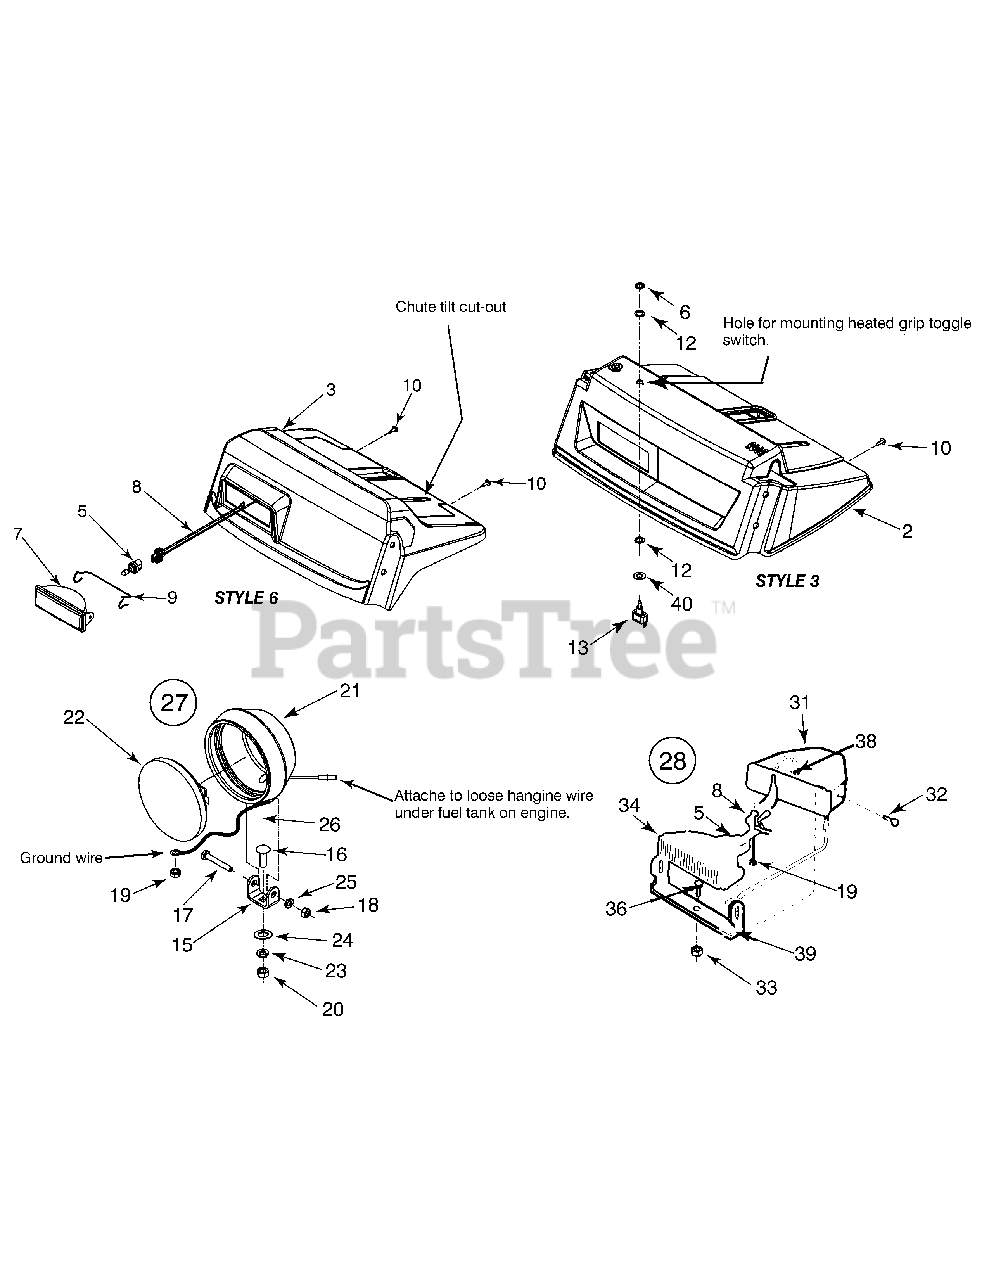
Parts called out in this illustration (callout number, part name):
2	Black Handle Panel (w/light cut out and chute tilt cut out) STYLE 3
2	Black Handle Panel (w/hole for top mounting light and chute tilt cut out) STYLE 3
2	Yellow Handle Panel (w/hole for top mounting light and chute tilt cut out) STYLE 3
2	Yellow Handle Panel (w/ light cut out, chute tilt cut out & heated grips) STYLE 3
2	Black Handle Panel (w/light cut out & w/o chute tilt cut out) STYLE 3
3	Grey Handle Panel (w/light cut out and chute tilt cut out) STYLE 6
3	Grey Handle Panel (w/hole for top mounting light and chute tilt cut out) STYLE 6
3	Black Handle Panel (w/hole for top mounting light and chute tilt cut out) STYLE 6
3	Black Handle Panel ( w/light cut out and chute tilt cut out) STYLE 6
5	Bulb #890, 12 V, 27 Watt
5	Bulb, #886, 12 V, 50 Watt (Style 3 w/heated grips)
7	Headlight Housing
8	Wire Harness
10	Hex Tapp Wash Hd. Scr. #10 x 5/8
12	Lock Ring - Toggle Switch
13	Toggle Switch,Single Throw (heated grips)
14	Dual Light Wiring Harness
15	Mounting Lamp Bracket
16	Carriage Bolt 5/16-18 x 1.00" Lg
17	Hex Screw 1/4-28 x 1.75 Gr 5
18	Hex Nut 1/4-28 Gr 5
19	Sems Hex Nut 1/4-20
20	Hex Nut 5/16-18 hd. Gr. 5
21	Lamp Housing
22	Sealed Beam 18 Watt CGE #4414-1
23	L-Wash 5/16 ID
25	L-Wash 1/4 ID
26	Ground Wire
27	Top Mount 18 watt Lamp Ass’y (sealed beam)
28	Top Mounting Halogen Lamp Assembly
31	Halogen Lamp Housing
32	Phillips Pan Hd. Scr. M4 x 16mm
33	Hex Flange Locknut 5/16-18 Gr. F Nylon
34	Lamp/Lens Housing Ass’y
36	Carriage Bolt 5/16-18 x .75
38	Grommet .38 ID X .50 OD X .12
39	Lamp Mounting Brkt.
40	Flat Washer .474 ID x .879 OD x .064
